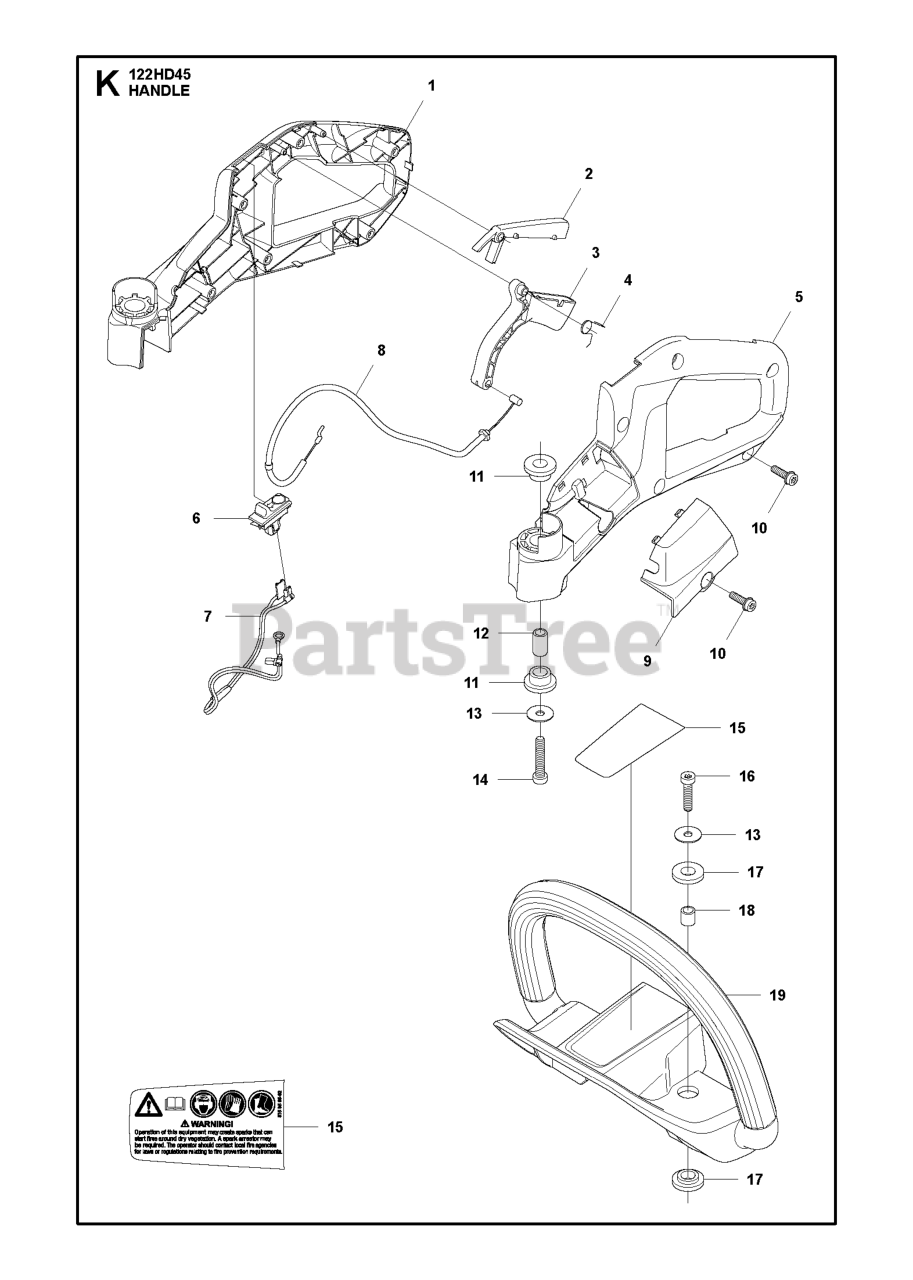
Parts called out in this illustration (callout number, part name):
2	WIRING
9	SPACER TUBE
10	WASHER BRB 8.4X17
11	SCREW
12	IGNITION SWITCH
15	IGNITION KEY
16	MICRO SWITCH
19	SCREW EHHM
21	CABLE CLAMP
22	Rivet
